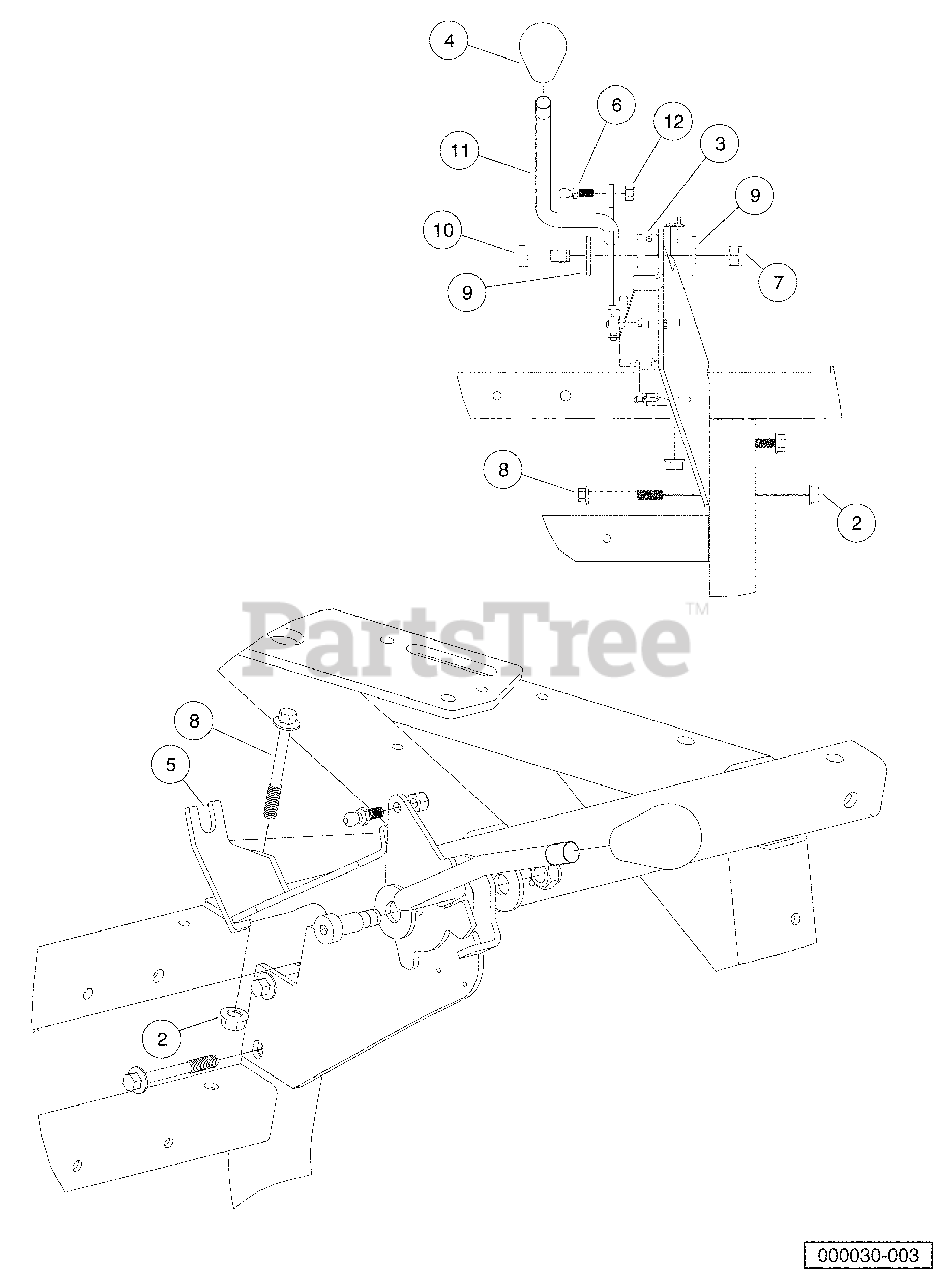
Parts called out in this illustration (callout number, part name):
1	Instl, Fnr, Shifter, Dom
2	Nut,m8,all Metal Lock
3	Bushing, Fnr
5	Weldment, FNR Shifter Bracket
6	Stud, Ball, .346 Dia
7	Locknut, M10x1.5 Nylon Insert
8	Bolt Flanged Head, M8 X 1.25 X 65
9	Washer, M12 Hard Regular
10	Shoulder Bolt,m12 X 20 M10 Thd
11	Weldment, FNR Shifter
12	Locknut, 1/4-28 Nylon Insert
13	Tie Wrap, 8" Nylon
